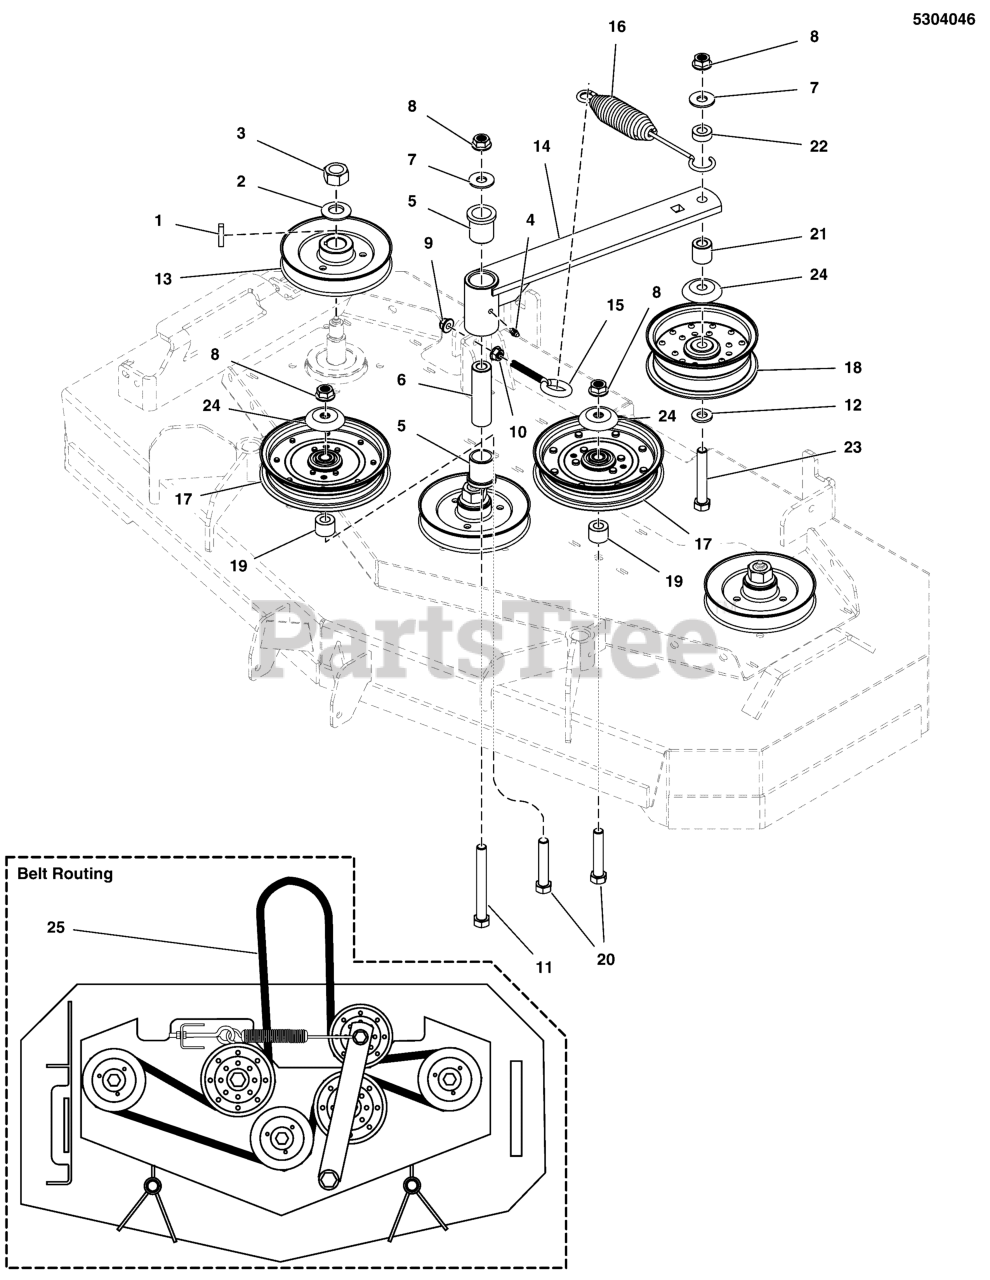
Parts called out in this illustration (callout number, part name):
1	KEY, 1/4" SQ. X 1-1/4
2	WASHER, 3/4 BELLEVILLE CL/ZC
3	NUT, 3/4-16 Hex
4	GREASE FITTING, 1/4-28 Straight
5	BUSHING, FLANGE
6	SPACER, .52 x 1.00 x 3.50
7	WASHER, 1/2" USSZ
8	NUT, Hex Flange, Nylock, 1/2-13
9	NUT, 3/8 - 16 HEX NYLOCK FLANGE
10	NUT, 3/8-16 Hex Large Serrated Flange
11	BOLT, 1/2-13 X 5" GD5 YZ
12	WASHER, 1/2" GD9 YZ
13	PULLEY, 5.540OB X .985ID, SINGLE B-SEC
14	WELD, IDLER ARM, 13.50 - BLK
15	EYEBOLT, 3/8-16 X 4, 2.13THRD, .75EYE, C
16	SPRING-EXT, 1.25OD X 9.3LG X .142WR, BLK
18	PULLEY, IDLER, 5.00 WIDE W/ .51 BORE
19	SPACER, .51 x 1.75 x .75
20	BOLT, 1/2-13 X 2-3/4 GD5 CZ
21	SPACER, .52 x 1.00 x 1.00
22	SPACER, .52 X 1.00 X .38, CZ
23	BOLT, 1/2-13 X 3-1/2, HEX HD, GD5, CZ (SV)
24	SHIELD, PULLEY BEARING, CZ
25	BELT, B-SEC, 129.15"EL, ARAMID, WRAPED
